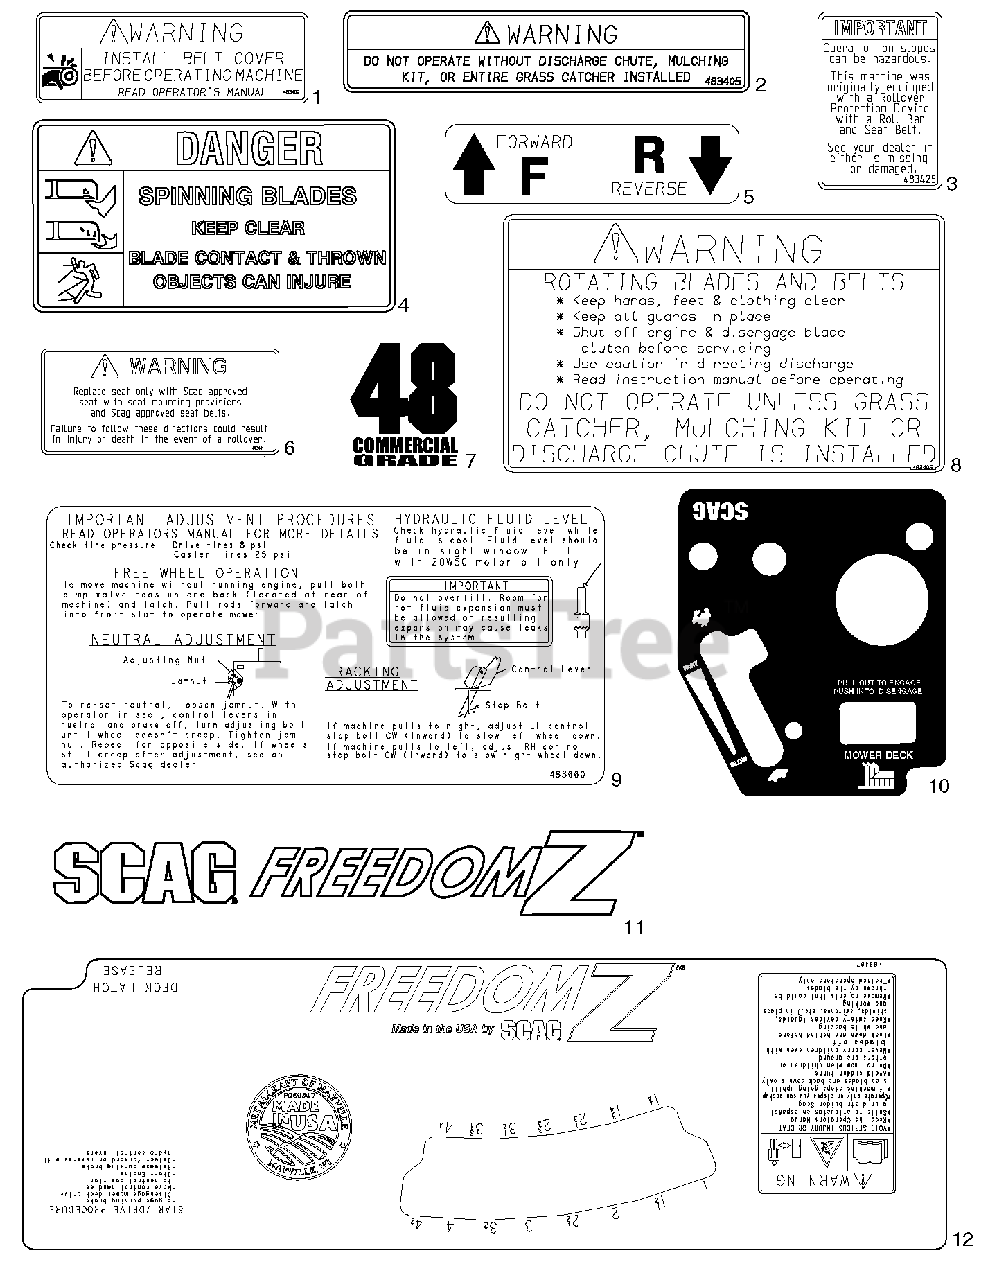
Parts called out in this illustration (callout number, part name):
1	Decal, Belt Cover
2	Decal, Warning
3	Decal, ROPS
4	Decal, Spinning Blades
5	Decal, Traction Control
6	Decal, Seat Replacement
7	Decal, 48 Commercial
7	Decal, 52 Commercial
8	Decal, Knives
9	Decal, Adjustment SFZ
10	Decal, Instrument Panel - SFZ48 & SFZ 52
11	Decal, Front SFZ
12	Decal, Cutting Height
